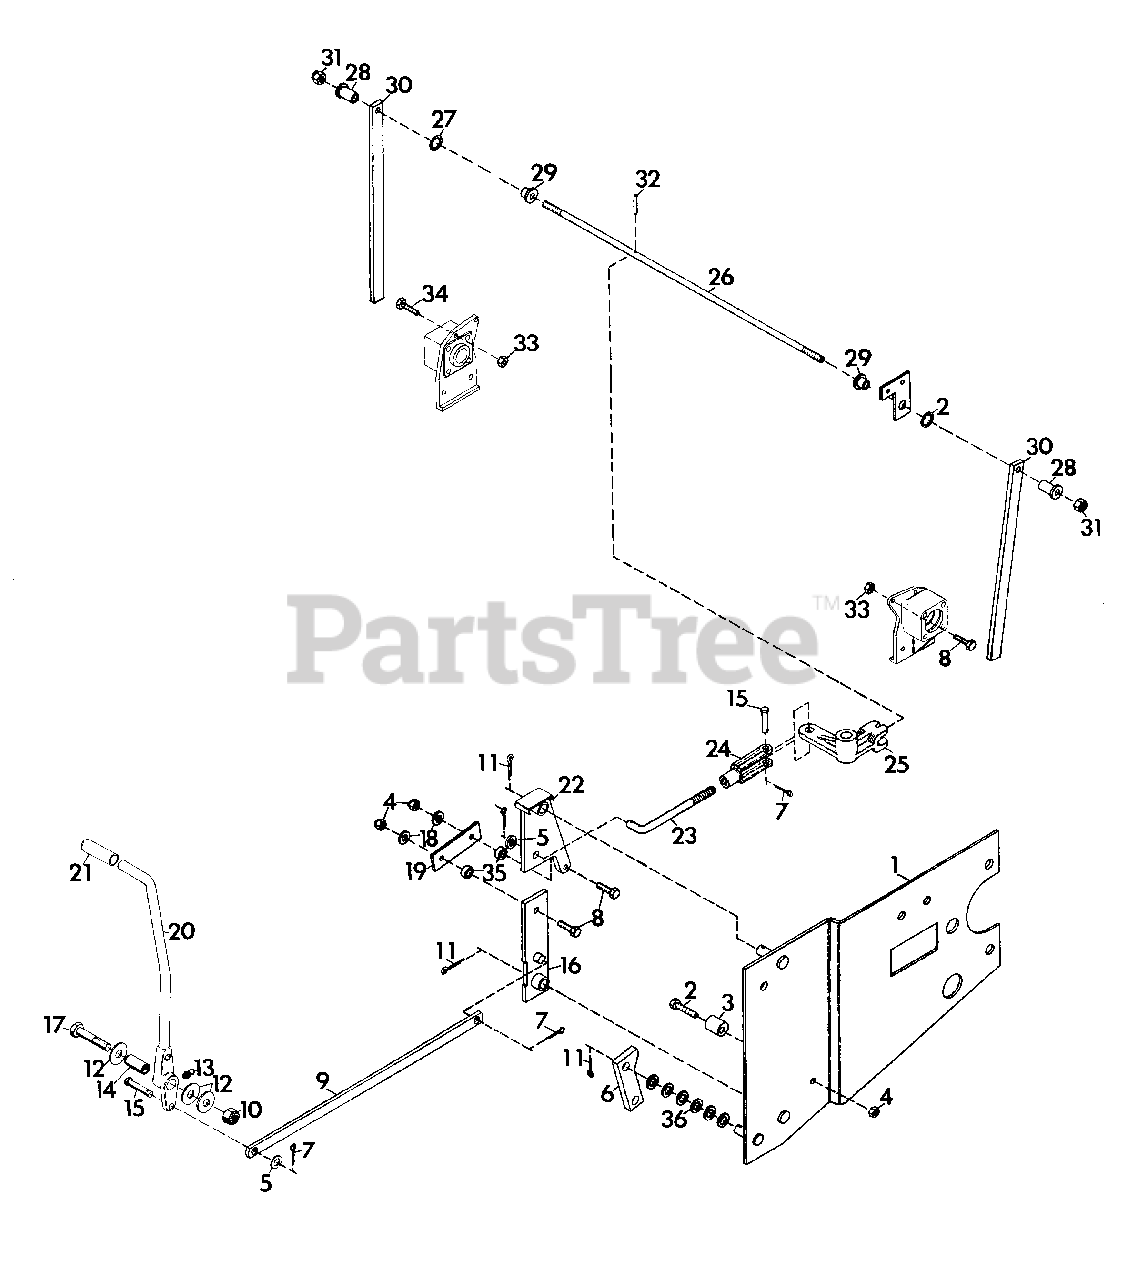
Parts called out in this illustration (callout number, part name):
1	WELDMENT, FWD-REV MTG. PLATE
2	BOLT, HEX 5/16-18X1.50
3	BUSHING
4	NUT, LOCK 5/16-18
5	WASHER, FLAT .406X.812X.065
6	CAM, BRAKE
7	PIN, COTTER .09X.75
8	BOLT, HEX 5/16-18X1.25
9	LINK, FWD-REV SHIFTER
10	NUT, LOCK 1/2-13
11	PIN, COTTER .125X1.00
12	WASHER, FLAT .562X1.375X.109
13	FITTING, LUBE 1/4-28
14	BUSHING, .505X.74X1.438
15	PIN, CLEVIS .375X.948
16	WELDMENT, OVER-CENTER ARM
17	BOLT, HEX 1/2-13X2.75
18	WASHER, FLAT .344X.688X.065
19	STRAP, OVER-CENTER
20	LEVER, FWD-REV
21	GRIP, HANDLE
22	WELDMENT, CLUTCH ARM
23	ROD, CLUTCH
24	CLEVIS, 3/8-24 ADJUSTABLE
25	LEVER, SLIDE ROD
26	ROD, FWD-REV CLUTCH
27	RING, RETAINING
28	BUSHING, FWD-REV SLIDE ROD
29	BUSHING, .513X.750X.625
30	SPRING, FWD-REV CLUTCH
31	NUT, LOCK 1/2-20
32	PIN, DOWEL
33	NUT, HEX 5/16-18
34	BOLT, HEX 5/16-18X1.00
35	BUSHING, .330X.500X.265
36	WASHER, FLAT .375X.734X.065
